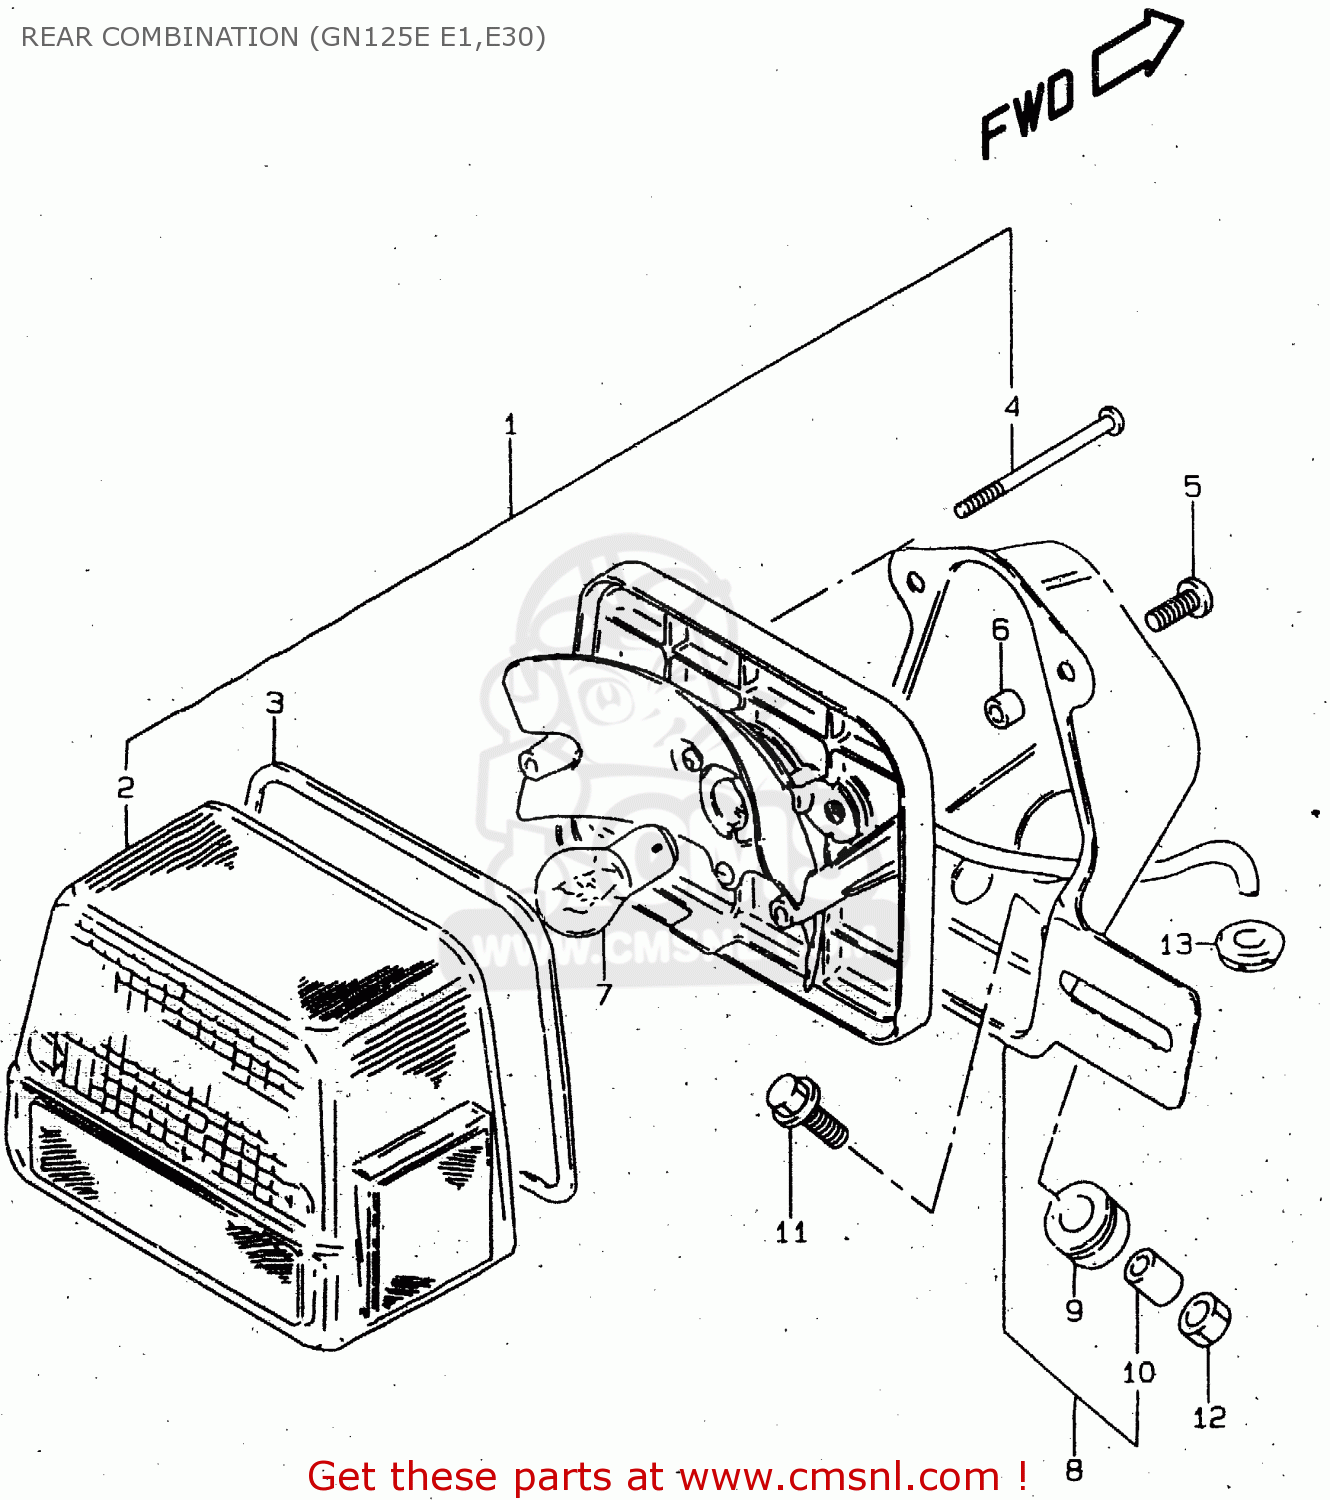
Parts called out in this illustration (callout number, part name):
1	LAMP UNIT,RR COMBNATION
2	LENS
3	GASKET (NAS)
4	SCREW
5	SCREW
6	SPACER
7	BULB(12V23W)
8	BRACKET UNIT,TAIL LAMP
9	CUSHION
10	SPACER
11	BOLT(6X25)
12	NUT 6MM
13	GROMMET
